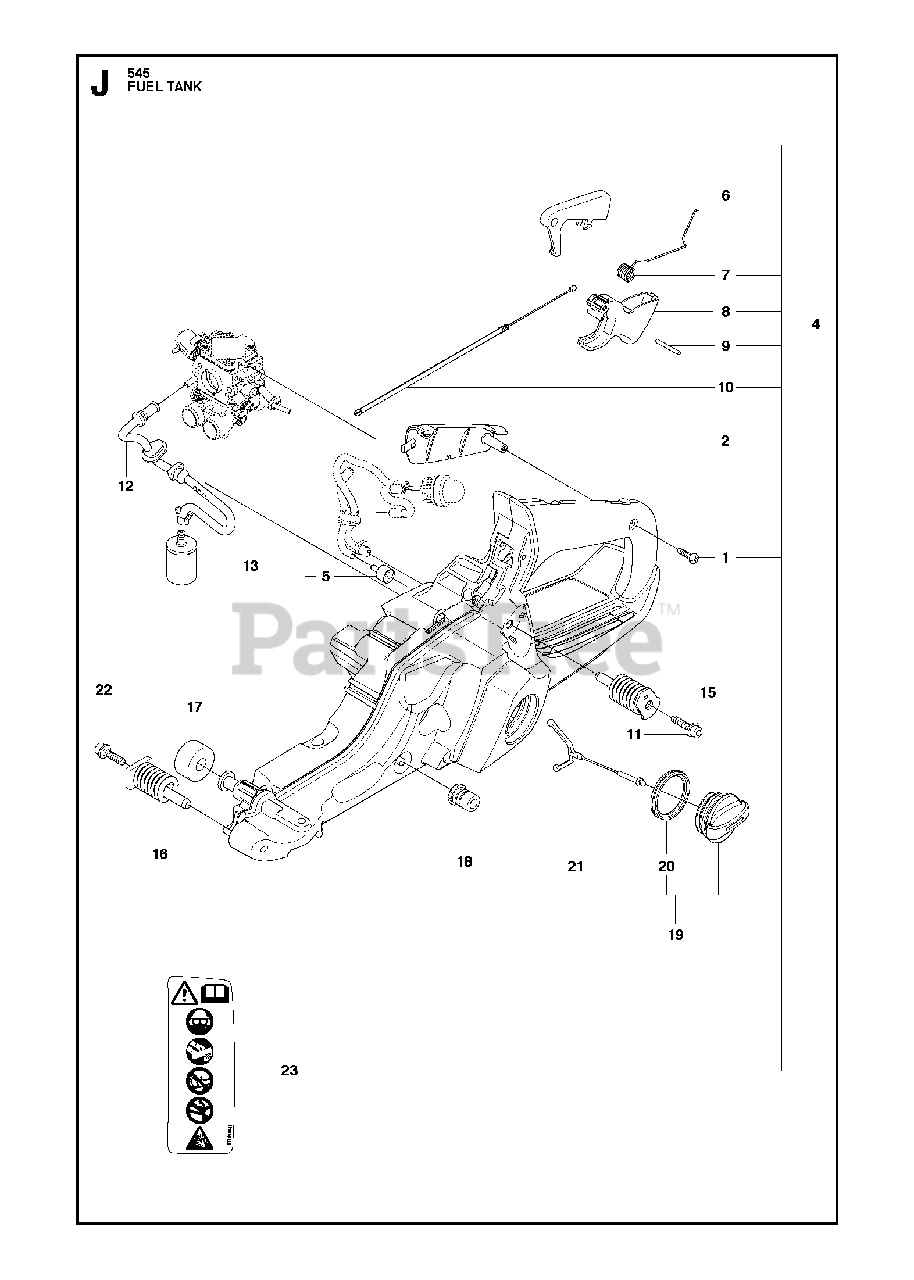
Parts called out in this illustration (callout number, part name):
1	SCREW
2	HANDLE INSERT
4	FUEL TANK ASSY 50CC ORANGE
5	FUEL TANK VENT
6	THROTTLE LOCKOUT
7	SPRING
8	THROTTLE
9	PIN
10	THROTTLE CABLE ASSY
13	FUEL FILTER
15	ANTIVIBRATION ELEMENT
16	ANITVIBRATION ELEMENT
17	DEFLECTION LIMITER
18	LATERAL SUPPORT
19	TANK CAP ASSY
20	SEALING
21	TANK LOCK
23	DECAL
